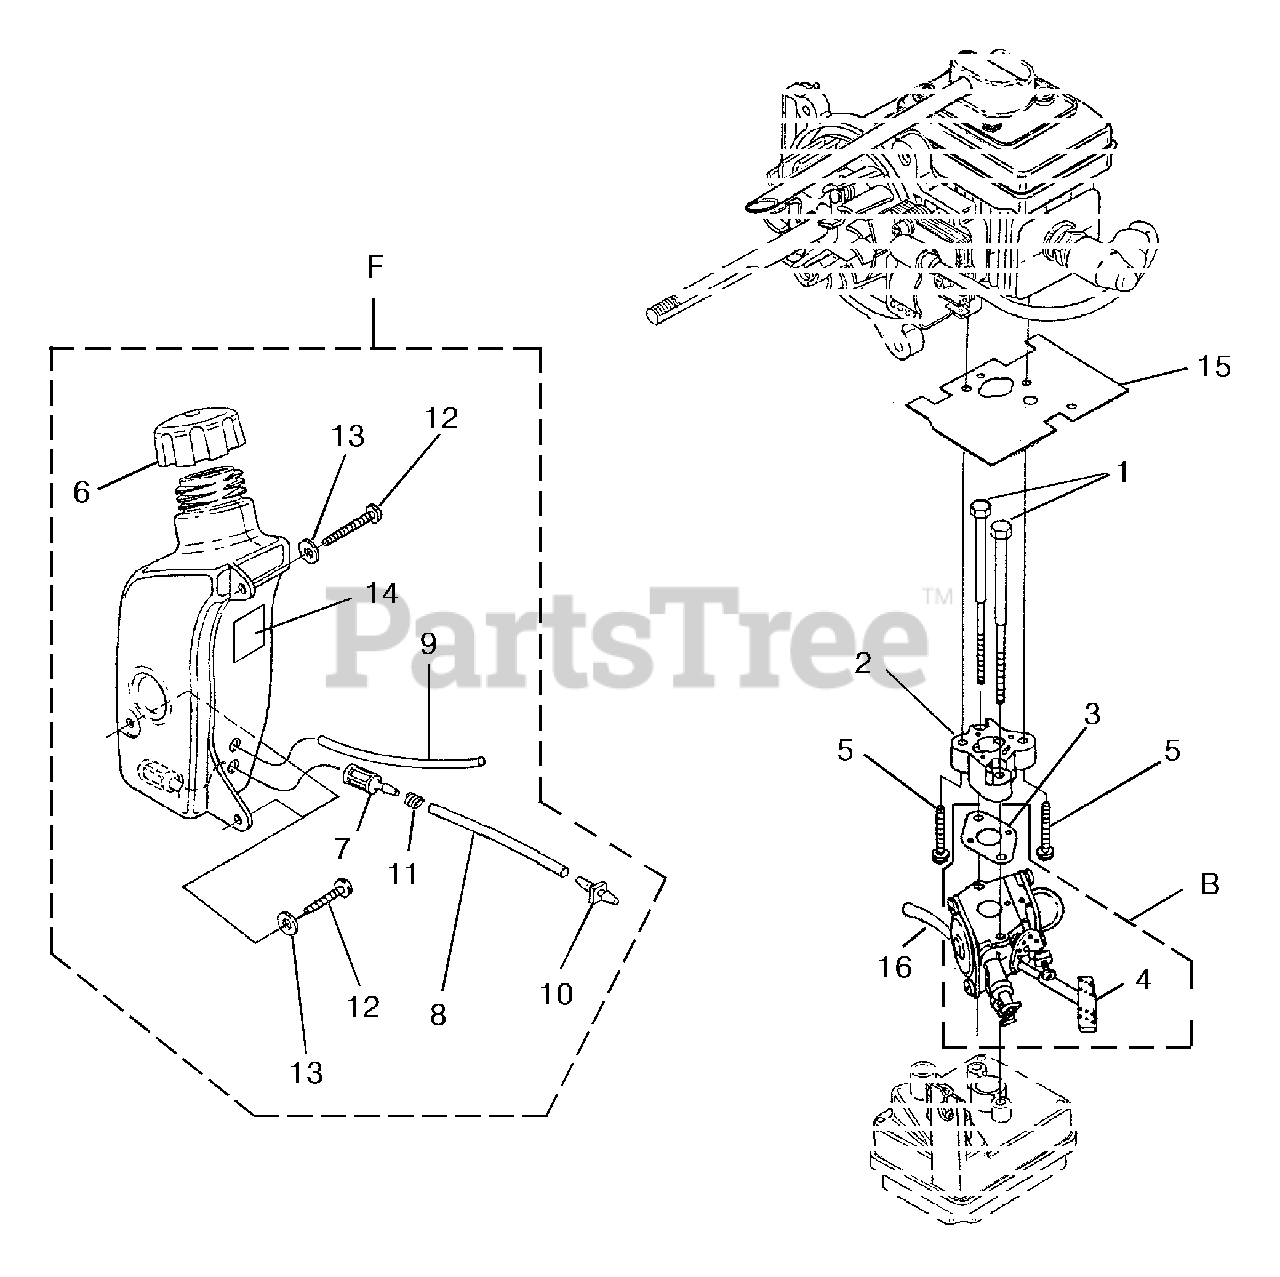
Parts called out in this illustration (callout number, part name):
1	Screw, Machine (10-24 x 2.8)
2	Heat Dam
3	Gasket, Carburetor
4	Lever, Choke (Zama)
5	Screw, Sems (10-24 x 1")
6	Fuel Cap
7	Fuel Filter
8	Tubing, Rubber (3")
9	Tubing, Rubber (5")
10	Fitting, Inlet
11	Clamp, Wire
12	Screw, Thread Forming (10-14 x 3/4)
13	Washer
14	Tape, Aluminum
15	Gasket, Heat Dam
16	Tubing, Rubber (5")
B	Carburetor Assembly
F	Fuel Tank Assy.
